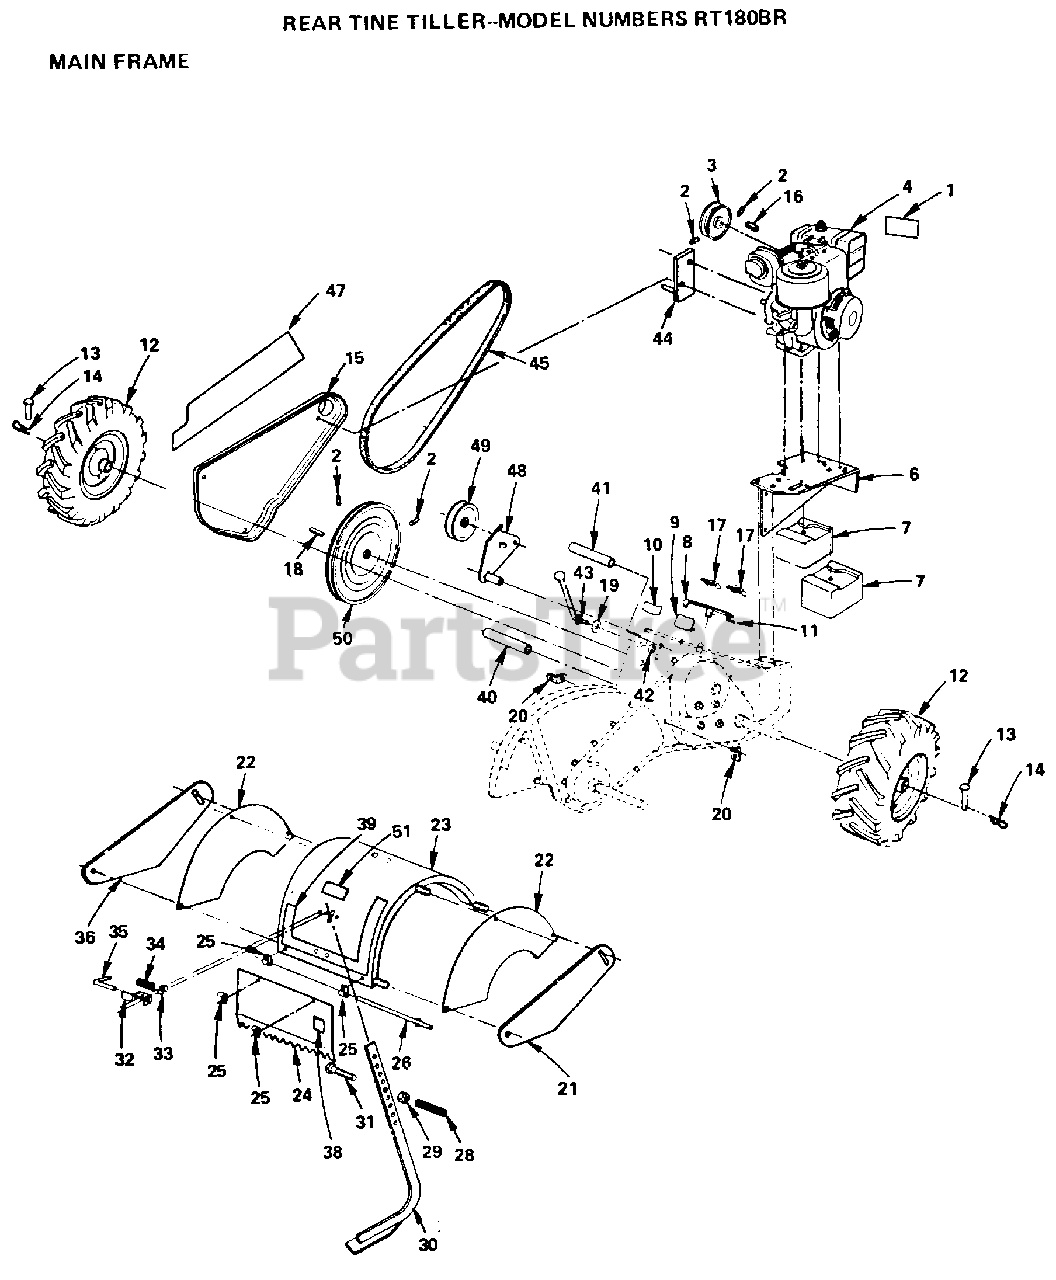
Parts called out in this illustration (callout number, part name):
2	SET SCREW
3	SHEAVE CRT
4	ENGINE - 8 HP
7	COUNTERWEIGHT CRT
8	LEVER ASSY T
9	PANEL TI
10	DECAL, SHIFT INDICATOR
12	WHEEL TI
13	RIVET.PAN HD.1.75
14	SPRING.RETAINER
16	KEY TI
17	CONDIUT CLIP T
18	KEY T
19	WASHER
20	TINE SHLD BRKT TI
25	HINGE CRT
26	PIN HINGE CRT
28	GRIP TI
29	NUT.HEX.3/8-16UNC
30	STAKE ASSY CRT
32	LATCH BRACKET TI
33	KLIP RING TI
34	SPRING TI
35	STAKE PIN TI
39	DECAL - TINE SHIELD
40	SPACER TI
41	SPACER TI
42	NUT FLANGE CRT
43	HANDLE LOCK CRT
47	DECAL - BELT GUARD
50	"SHEAVE 10"" CRT"
51	DECAL - DEPTH ADJUSTMENT
